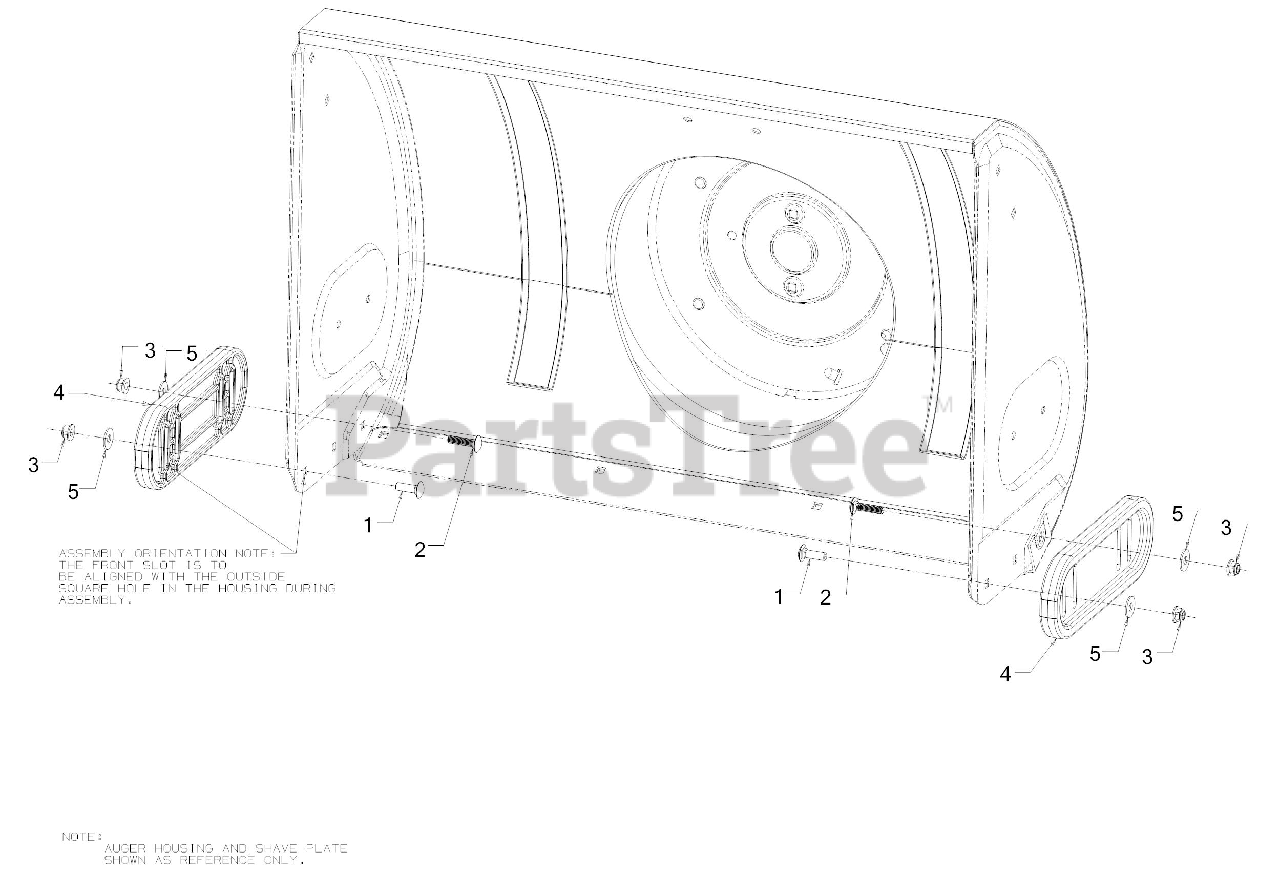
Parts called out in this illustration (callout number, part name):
1	CARRIAGE BOLT 5/16-18 x 1.00
2	CARRIAGE BOLT 5/16-18 X 1.25
3	FLANGE LOCK NUT 5/16-18
4	DELUXE SKID SHOE (POLY BLUE)
5	FLAT WASHER
